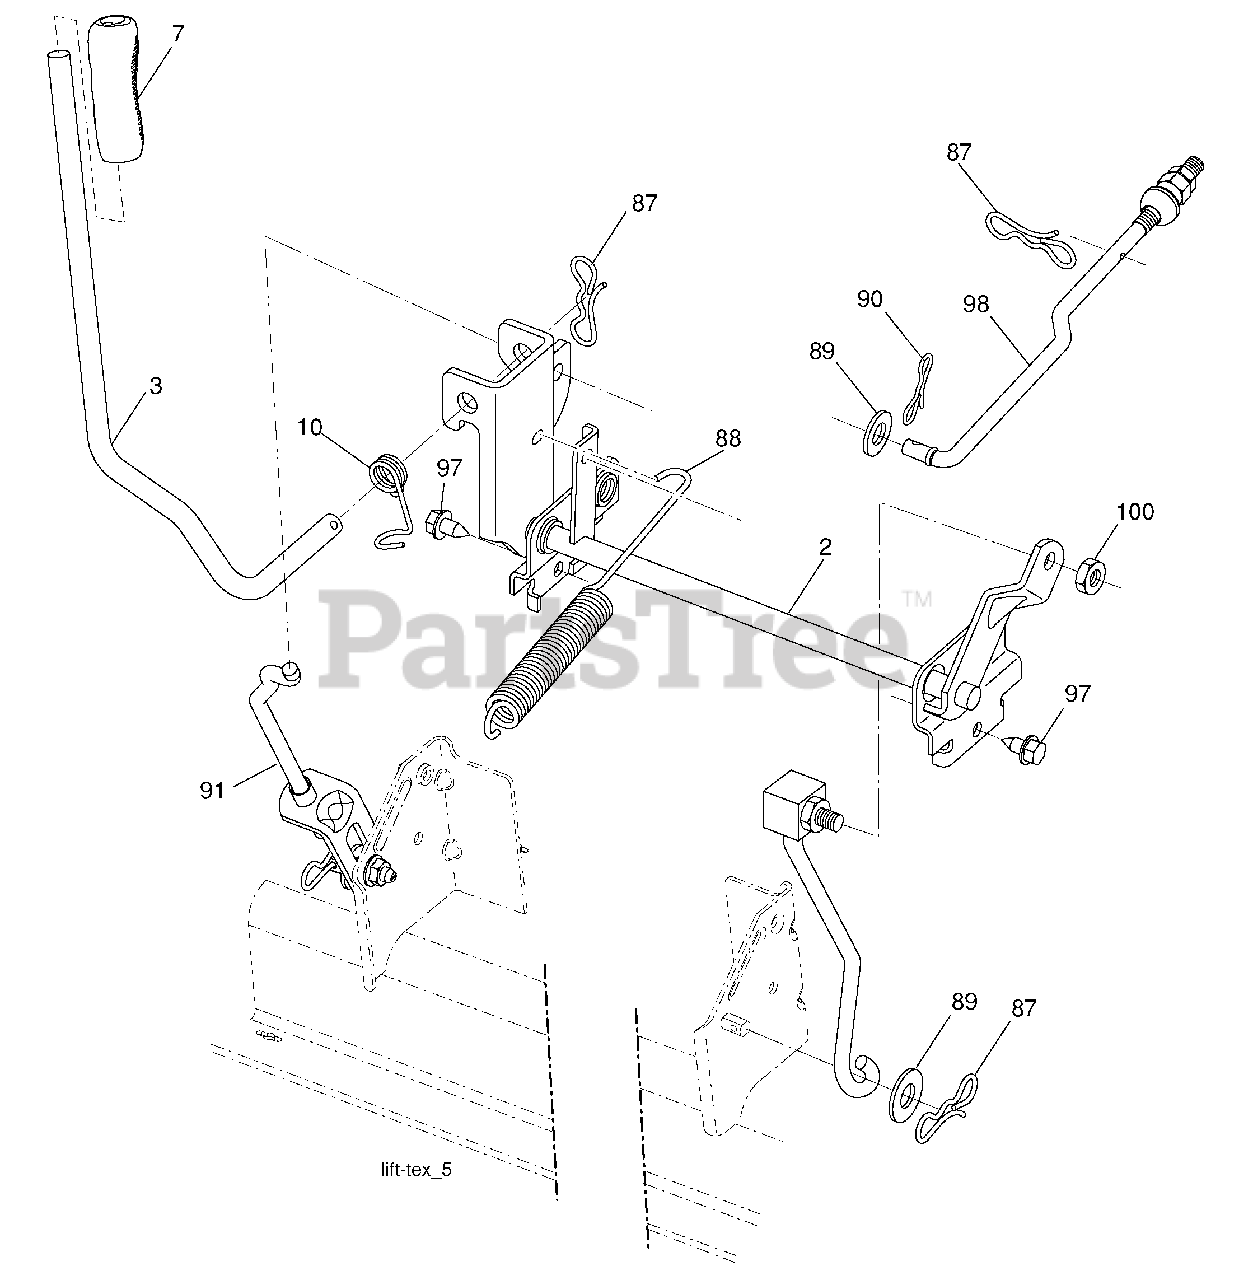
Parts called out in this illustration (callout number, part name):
2	Shaft Asm., Lift
3	Lever Asm., Lift RH
7	Grip, Lever
10	Spring Torsion
87	Pin Cotter 7/16 Bow Tie Lock
88	Spring Lift Assist
89	Washer Clear Zinc
90	Pin Cotter 5/16 Bow Tie Lock
91	Link Asm. Lift Rear
97	Screw 3/8-16 x .75 Smgml Tap/R.Z
98	Link Lift Susp. Front Mower
100	Nut Centerlock 3/8-16 unc
